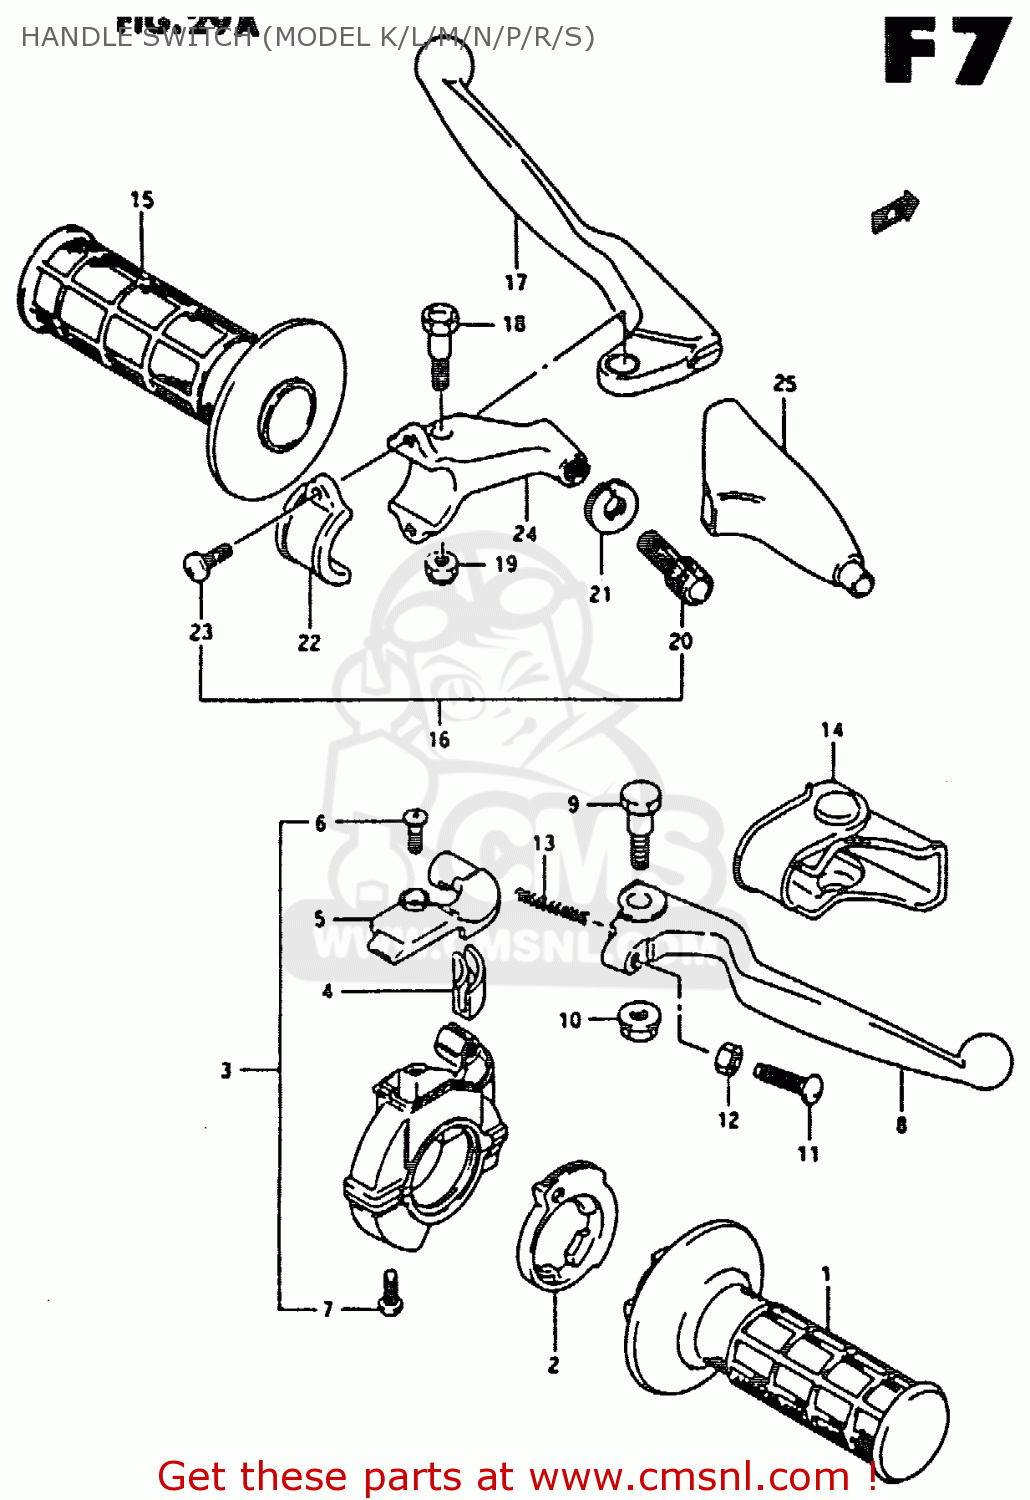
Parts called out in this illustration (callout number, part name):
1	GRIP,THROTTLE
2	ROTOR,THROTTLE GRIP
3	CASE ASSY,THROTTLE
4	GUIDE PIECE,THROTTLE
5	COVER,THROTTLE CASE
6	SCREW,UPPER
7	SCREW
8	LEVER,BRAKE
9	BOLT,BRAKE LEVER
10	NUT,BRAKE LEVER
11	BOLT,ADJUST
12	NUT ,5MM
13	SPRING,RETURN
14	COVER,BRAKE LEVER
15	GRIP,L
16	LEVER ASSY,CLUTCH
17	LEVER,CLUTCH
18	BOLT,LEVER
19	NUT 6MM
20	ADJUSTER,CABLE
21	NUT,CABLE ADJUSTER
22	BRACKET,CLUTCH LEVER HOLDER
23	SCREW(5X14)
24	HOLDER,CLUTCH LEVER
25	COVER,CLUTCH LEVER
